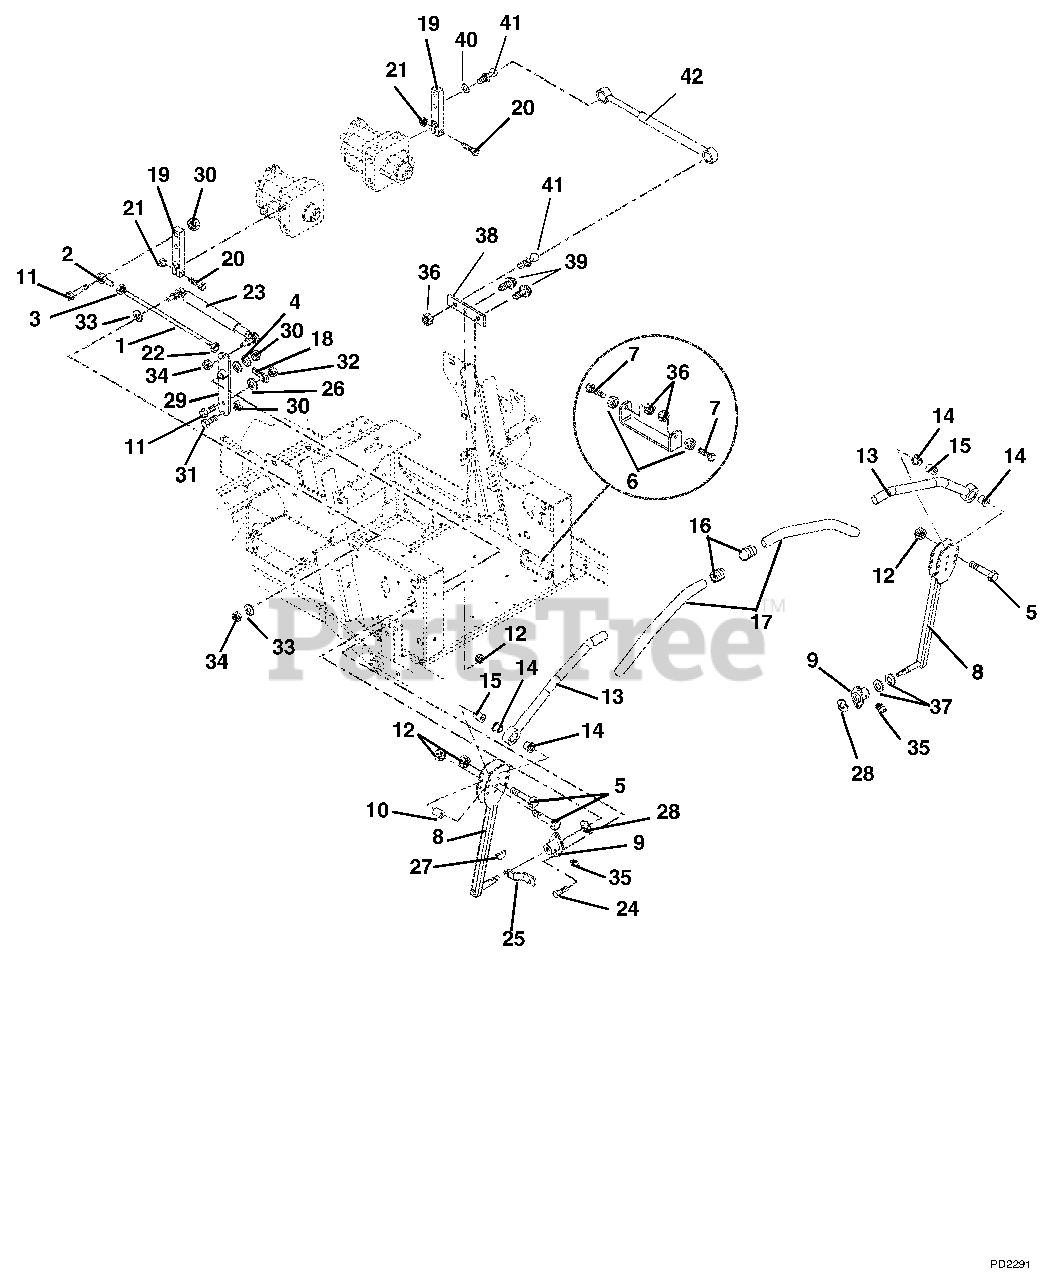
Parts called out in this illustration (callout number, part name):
1	Tie Rod Assembly
2	Rod End, .38 Right Hand
3	Nut-Jam .375-24
4	Washer-Flat-Steel .38 x .875 x .083
5	Bolt-Hex .31-18 x 1.75 Grade 5
6	Nut-Jam .312-18
7	Bolt-Hex .31-18 x 1.50 Grade 2
8	Weldment, Control Arm
9	Bushing-Flange .515 x .750 x .745 x 1.00
10	Eccentric
11	Bolt-Hex .38-16 x 1.75 Grade 5
12	Nut-Locking-Nylon .312-18
13	Handle Weldment Left-Hand
13	Handle Weldment Right-Hand
14	Bushing-Flange-Nylon .762 x 1.48 x .44
16	Caplug- Handlebar
17	Grip-Handlebar
18	Rod End, .38 Left Hand
19	Arm, Pump Actuating
20	Bolt-Hex .25-20 x 1.25 Grade 5
21	Nut-Locking-Nylon .250-20
22	Nut-Jam .375-24 Left Hand
23	Dampener, Self-Centering
24	Bolt-Hex .31-18 x .75 Grade 5
25	Footboard, Lock-Up
26	Washer-Locking .38 x .094 Regular
27	Key-Woodruff .13 x .63
28	Wave Washer
29	Weldment, Pivot Arm
30	Nut-Locking-Nylon .38-16
31	Bolt-Hex .38-16 x 1.25 Grade 5
32	Nut-Locking Top .375-16 Grade C
33	Washer-Flat-Steel .38 x .875 x .083
34	Nut-Locking-Nylon M8-1.25
35	Fitting-Lube .25-28 x .256
36	Nut-Locking-Center .31-18
37	Washer-Flat-Steel .63 x 1.005 x .062
38	Bracket, Damper Mounting
39	Screw-Tapping .31-18 x .75 Hex Washer Head
40	Washer-Locking .31 x .078
41	Stud- Ball
42	Damper, Control
